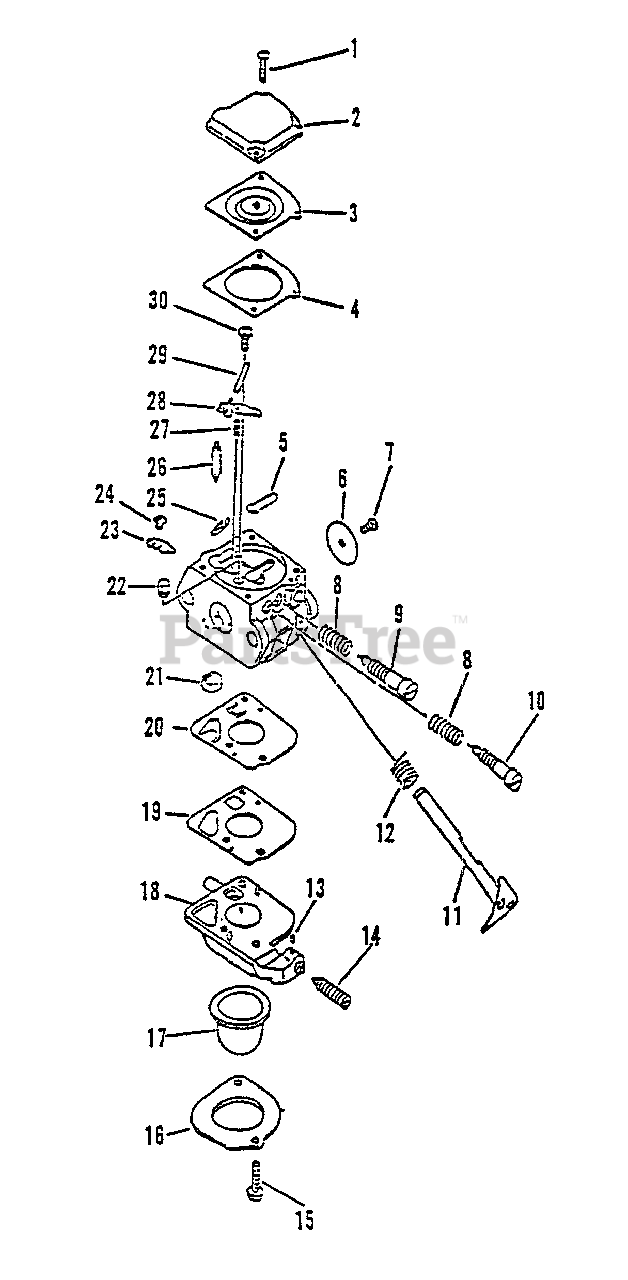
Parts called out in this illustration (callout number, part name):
2	COVER, DIAPHRAGM
3	DIAPHRAGM
4	GASKET, METERING
5	PLUG, WELCH
6	VALVE, THROTTLE
8	SPRING, NEEDLE
9	NEEDLE, HIGH SPEED
10	NEEDLE, IDLE
11	SHAFT, THROTTLE
12	SPRING, THROTTLE RETURN
13	PIECE, FRICTION
16	RETAINER
17	BULB, PURGE
18	BODY ASSY, PURGE
21	STRAINER
22	NOZZLE, CHECK VALVE
23	LEVER, THROTTLE
26	VALVE, NEEDLE
27	SPRING
28	LEVER, METERING
29	PIN
